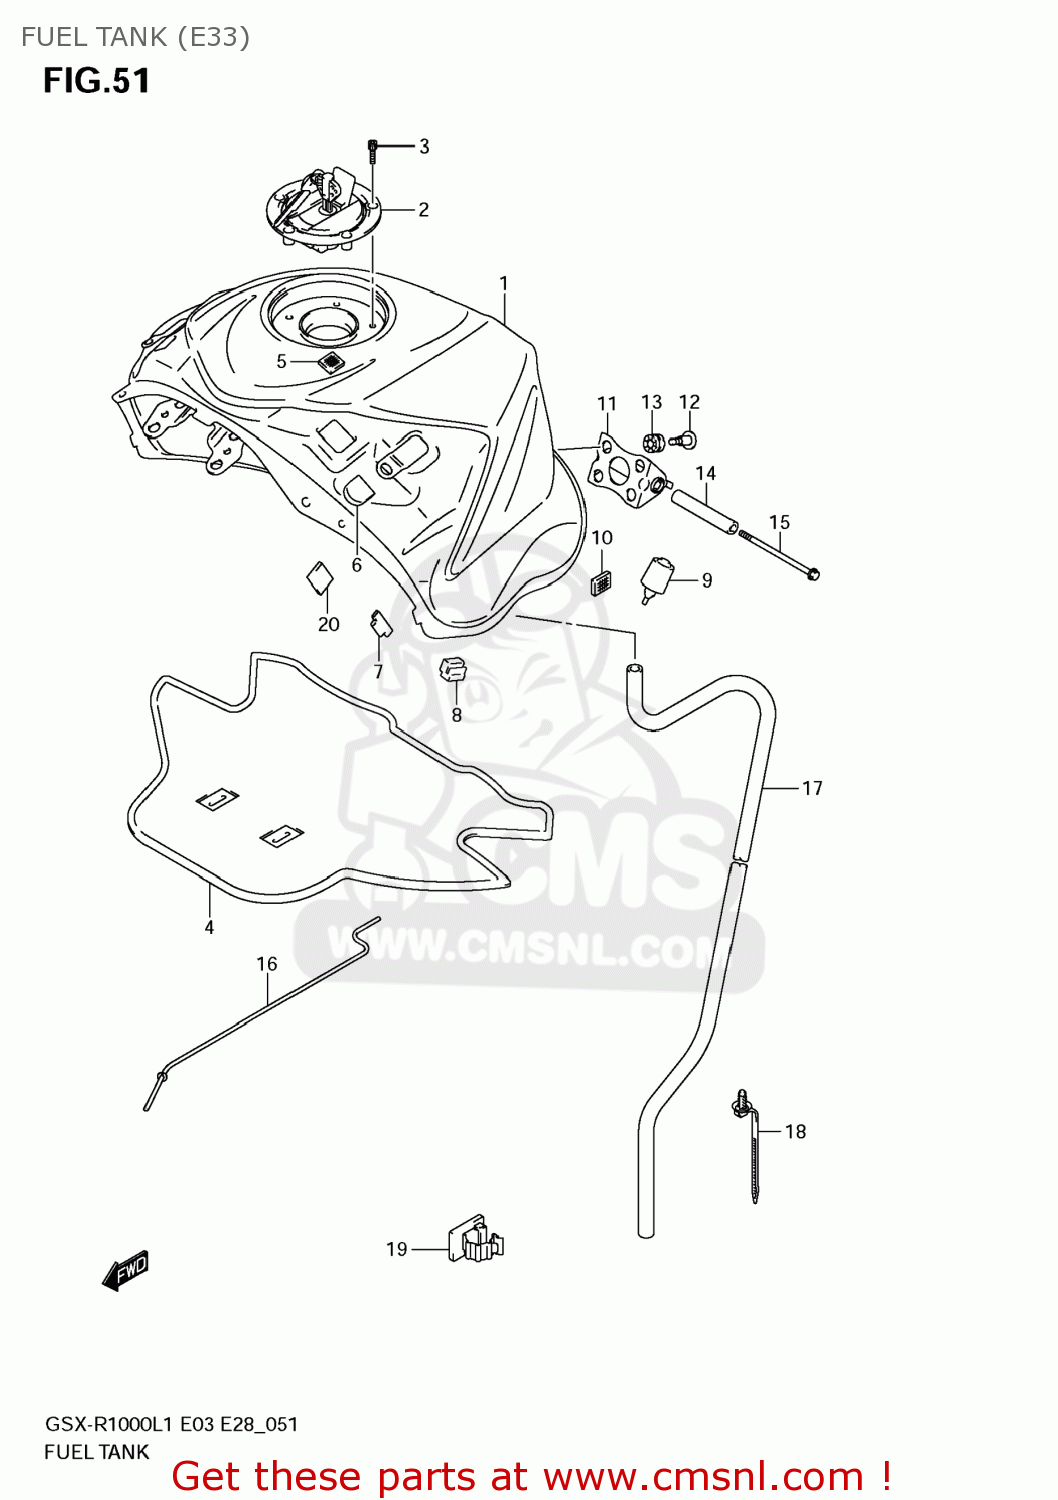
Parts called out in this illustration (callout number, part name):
1	TANK ASSY,FUEL
2	CAP SET,FUEL TANK
3	BOLT(5X20)
4	SHIELD,FUEL TANK HEAT
5	FASTENER
6	CUSHION
7	CUSHION,FUEL TANK COVER
8	CUSHION,FUEL TANK SIDE
9	CUSHION,FUEL TANK RR
10	FASTENER
11	BRACKET,FUEL TANK NO.1
12	SCREW(6X22)
13	CUSHION
14	SPACER,FUEL TANK RR
15	BOLT(6X110)
16	STAY,FUEL TANK
17	HOSE,FUEL TANK WATER DRAIN
18	CLAMP(L:154)
19	CLAMP
20	PAD
